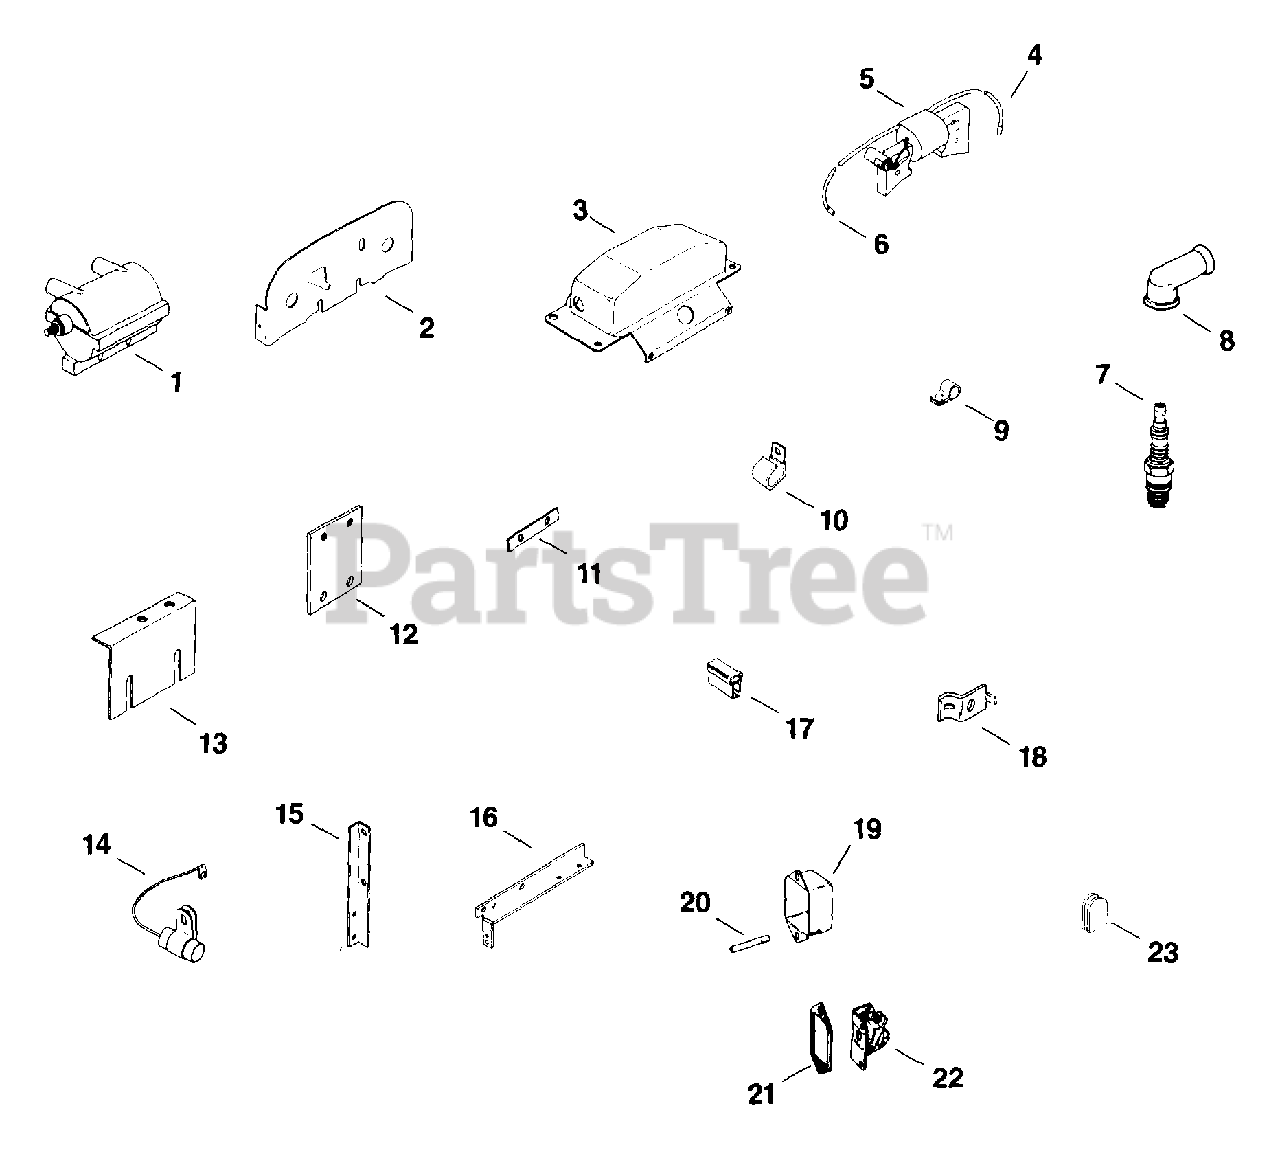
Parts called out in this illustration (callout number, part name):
4	STATOR - DISCONTINUED
6	CONDENSER
7	SPARK PLUG USE 25 132 10-S
8	BOOT - (#DSC)
19	COVER - DISCONTINUED
21	GASKET, POINT COVER
23	GROMMET
220074-S	DIAPHRAGM
